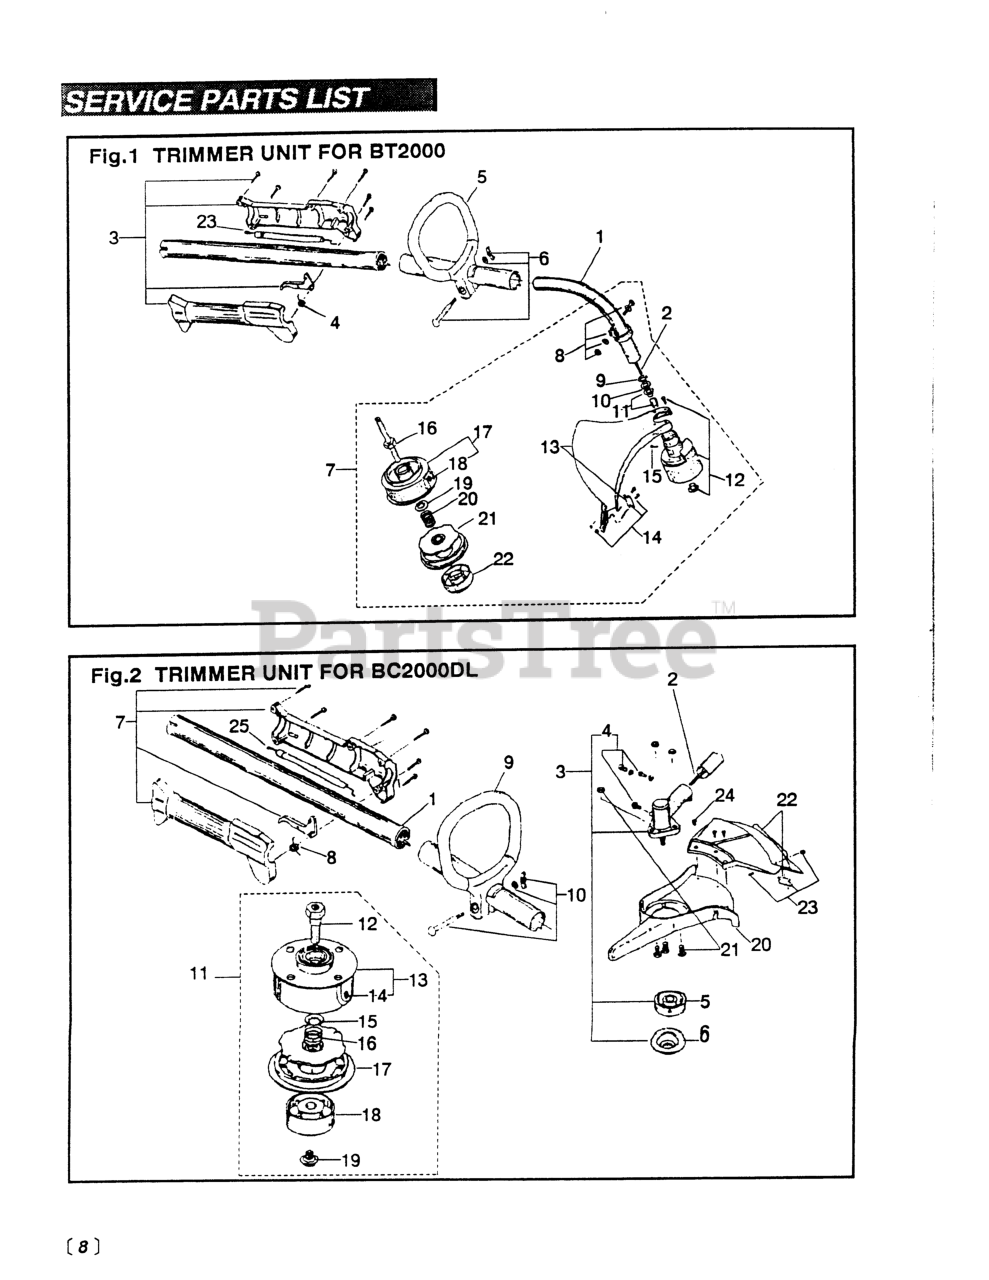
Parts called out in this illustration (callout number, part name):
1	SHAFT ASSEMBLY (BT)
4	SPRING, THROTTLE TRIGGER
7	CUTTING HEAD ASSEMBLY
8	CLAMP ASSY, LOWER
9	RING, RETAINING
10	WASHER
11	ASSY, BUSHING HOUSING
12	SCREW, GUARD MTG (SET)
14	BLADE ASSEMBLY
15	SET SCREW, ANTI-ROTATION
17	OUTER SPOOL ASSEMBLY
18	EYELET
19	WASHER, EYELET
